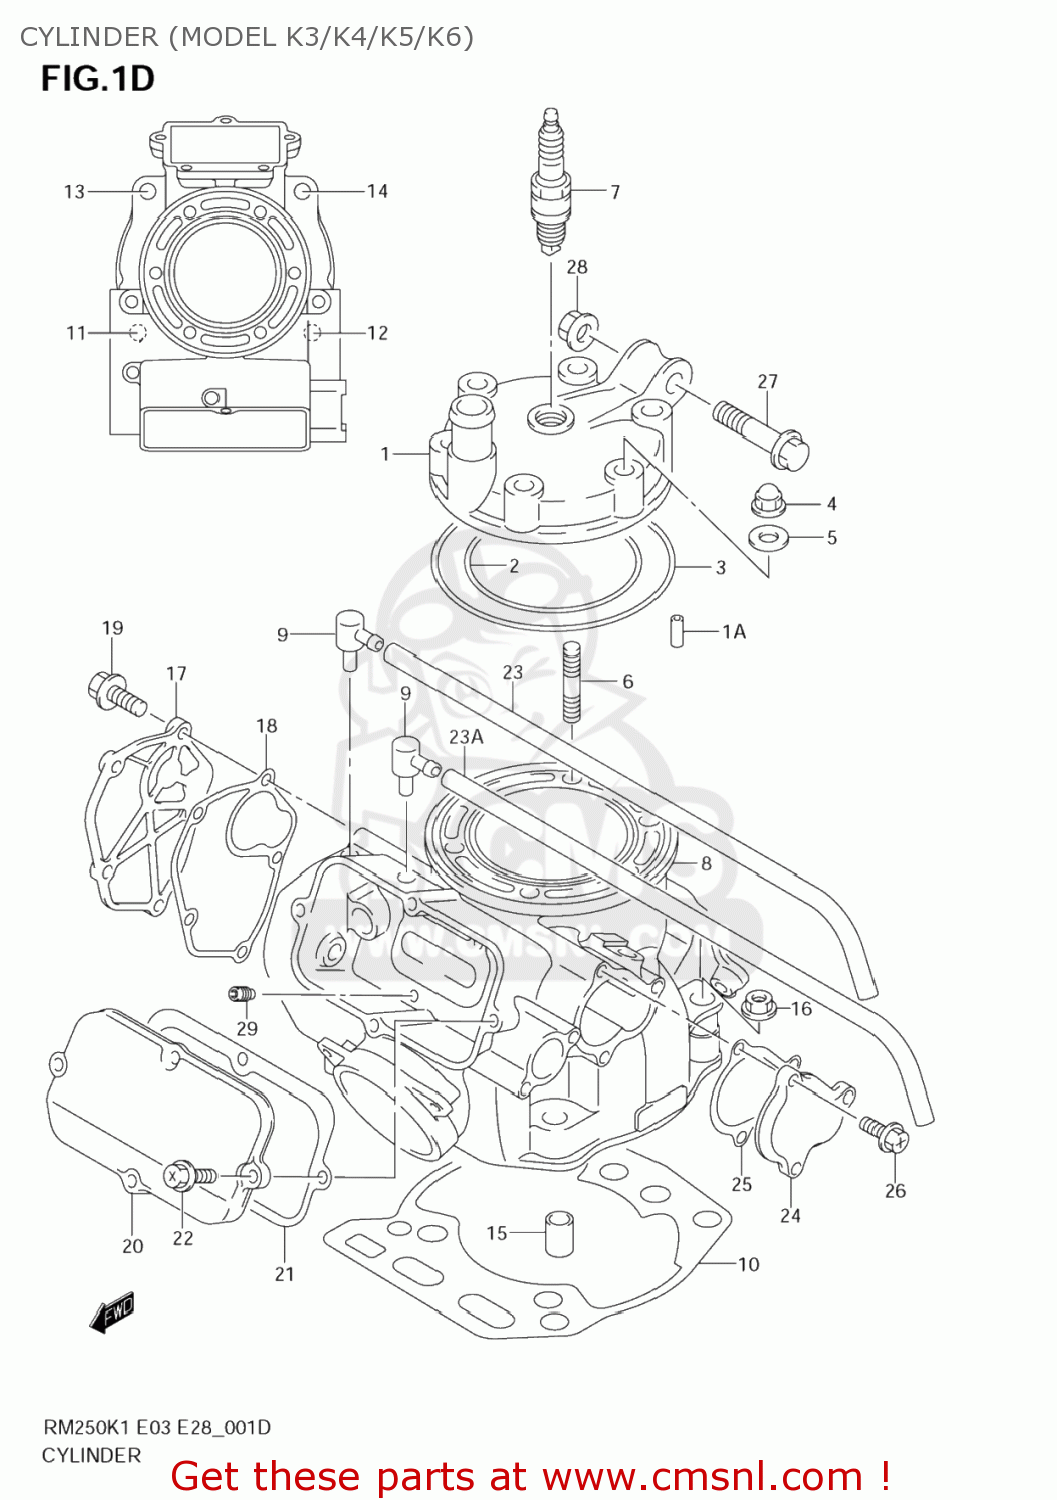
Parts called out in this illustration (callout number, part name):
1	HEAD,CYLINDER
1A	PIN
2	O RING,CYLINDER HEAD NO.1
3	O RING,CYLINDER HEAD NO.2
4	NUT
5	GASKET(8.5X17X2.3) (NAS)
6	BOLT,STUD
7	PLUG,SPARK(BR8EG)
8	CYLINDER SET
9	UNION,BREATHER HOSE
10	GASKET,CYLINDER (NAS)
11	STUD 10X30
12	STUD BOLT (L:40)
13	STUD,M10X1.25X
14	BOLT,STUD
15	PIN(13X10.4X20)
16	NUT
17	COVER,CYLINDER NO.1
18	GASKET,CYLINDER COVER NO.1 (NAS)
19	BOLT,CYLINDER
20	COVER,CYLINDER NO.2
21	GASKET,CYLINDER COVER NO.2 (NAS)
22	BOLT,CYLINDER
23	HOSE(5X8.2X600)
23A	HOSE(5X8.2X600)
24	COVER,CYLINDER NO.3
25	GASKET,CYLINDER COVER NO.3 (NAS)
26	BOLT,CYLINDER
27	BOLT(10X48)
28	NUT
29	SCREW,EXHAUST VALVE DRAIN
